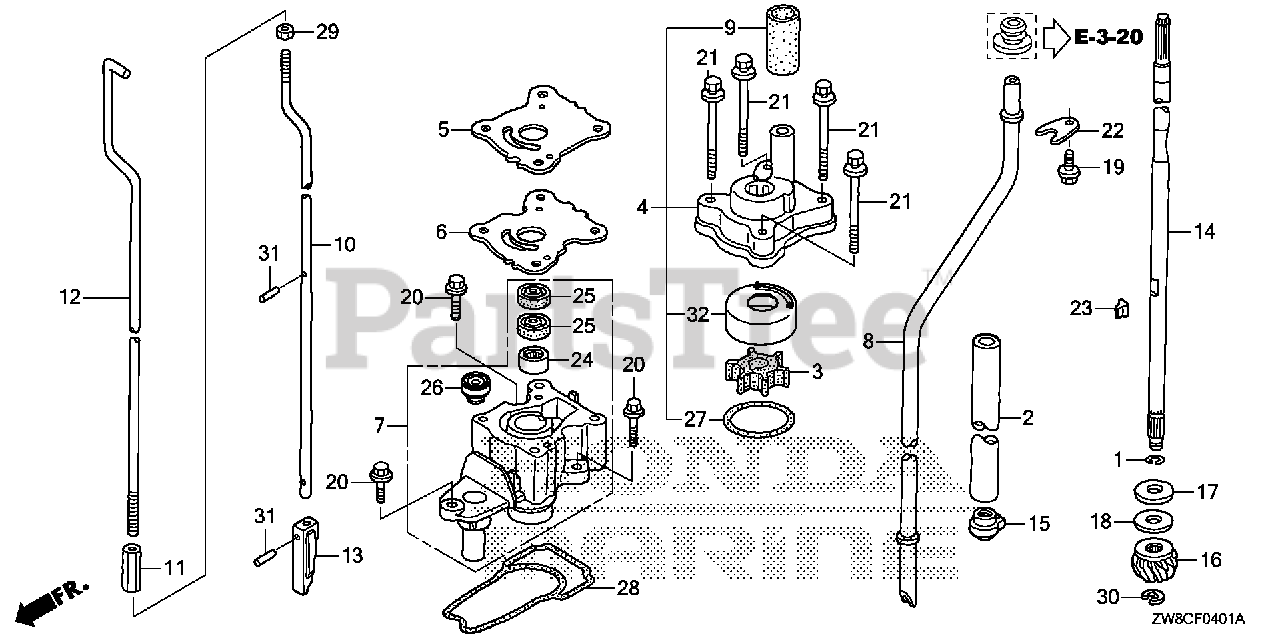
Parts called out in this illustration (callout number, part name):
1	CLIP, VALVE GUIDE
2	GUIDE, OIL (UL)
3	IMPELLER, PUMP (UL)
4	HOUSING ASSY., IMPELLER
5	COVER, IMPELLER
6	GASKET, IMPELLER
7	HOUSING, WATER PUMP (UL)
8	TUBE, WATER (UL)
9	RING, WATER TUBE SEAL
10	ROD B, SHIFT (UL)
11	JOINT, SHIFT ROD
12	ROD A, SHIFT (L)
13	ROD, PUSH
14	SHAFT, VERTICAL (UL)
15	SLINGER, OIL (UL)
16	GEAR, PINION
17	WASHER A, THRUST BEARING
18	WASHER B, THRUST BEARING
18	WASHER C, THRUST BEARING
19	BOLT, FLANGE (6X12) Use from Frame SN 1005249.
20	BOLT, FLANGE (6X20) (ENGINE NO.)
21	BOLT-WASHER (6X90)
22	PLATE, WATER TUBE SETTING
23	KEY, WOODRUFF
24	BEARING, NEEDLE (15X21X12)
25	SEAL, WATER (15X24X5)
26	SEAL, WATER (6MM)
27	O-RING (42.2X2.4)
28	O-RING, WATER PUMP HOUSING
29	NUT, HEX. (6MM)
30	E-RING (8MM)
31	ROLLER (2.5X11.8)
32	LINER, PUMP
